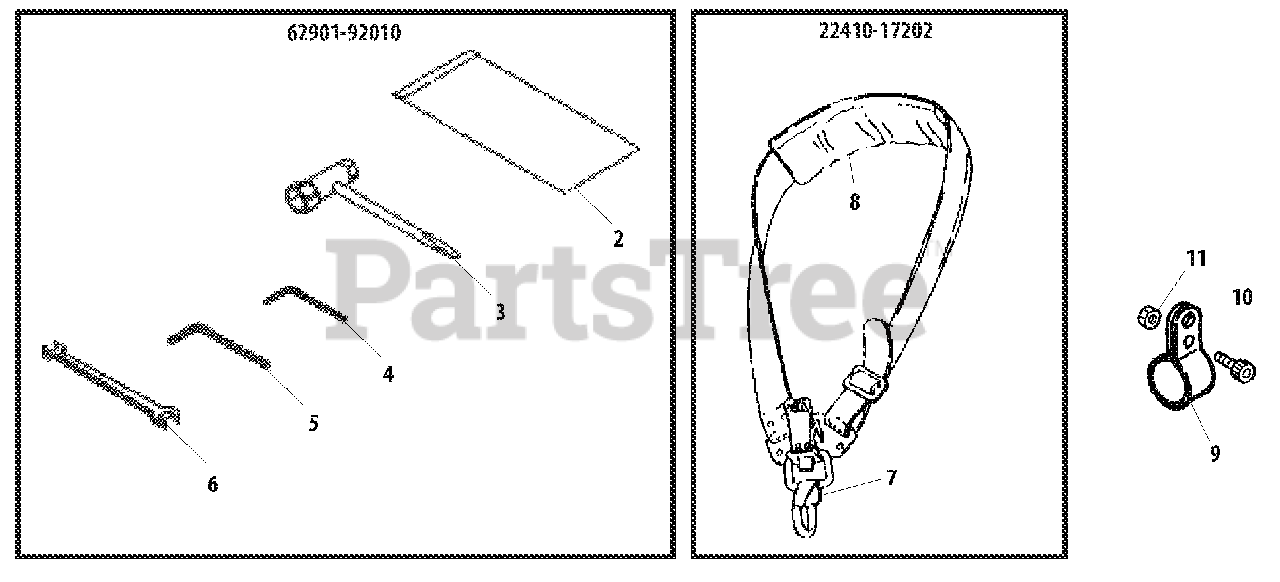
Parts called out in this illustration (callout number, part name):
2	BAG, TOOL
3	T-WRENCH - 13X16mm
4	HEX KEY - 3mm
5	HEX KEY - 4mm
6	SPANNER - 8X10mm
7	HOOK
8	PAD
9	BRACKET
10	SCREW - 5X12
22410-17202	STRAP ASSY
62901-92010	TOOL KIT
